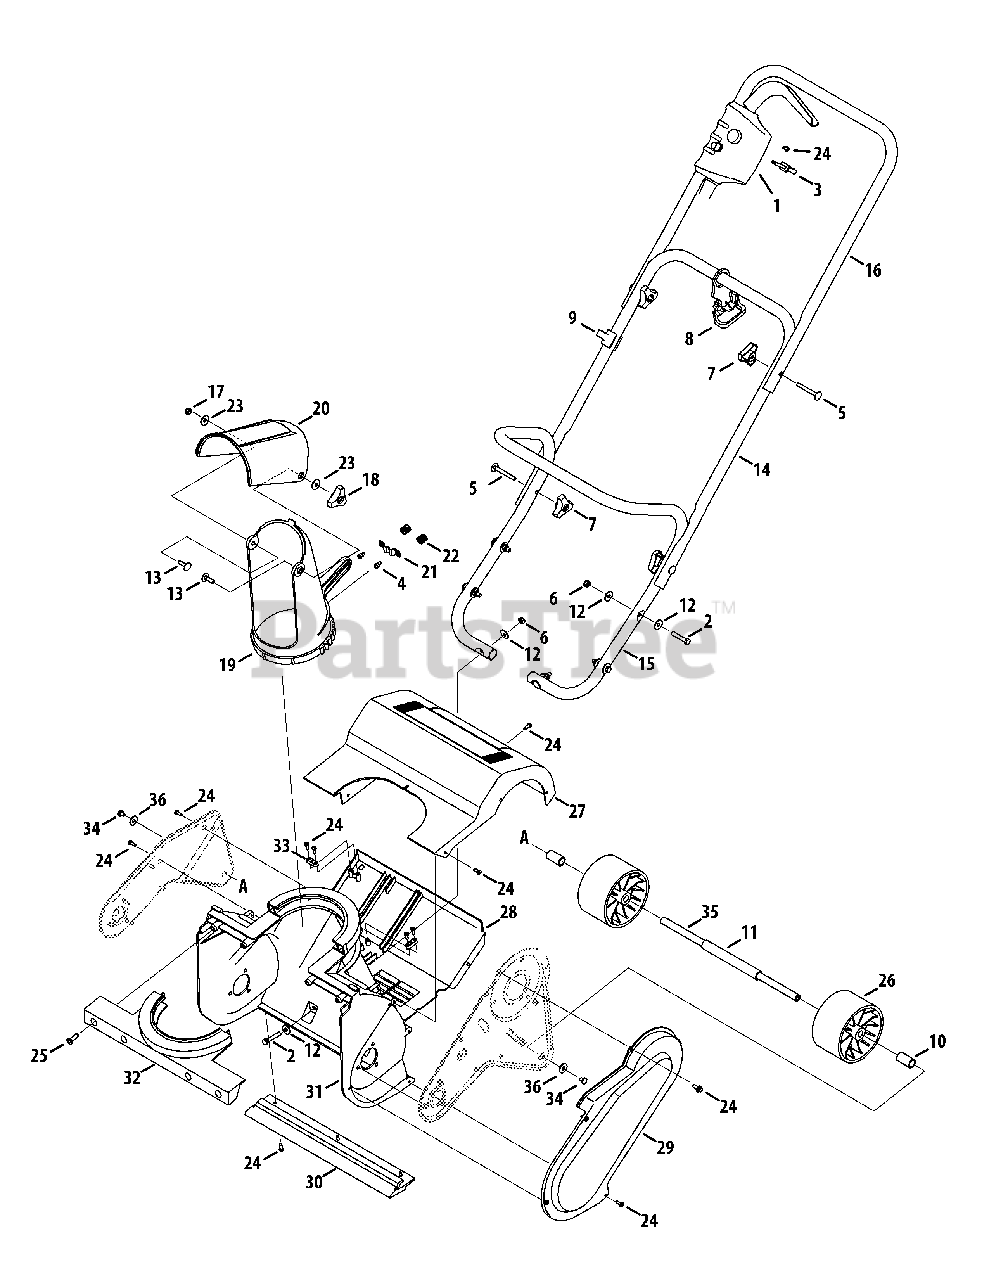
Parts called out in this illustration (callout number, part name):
1	Switch, Assembly
2	Screw, M6-1, 35.00
4	Screw, Shoulder, 6.12 x 4.00
5	Screw, Carriage, M6-1,45, Cl 8.8
6	Nut, Hex Lock, M6-1, Nylon
7	Knob, M6
8	Retainer, Cord
9	Cable, Guide
10	Spacer, 13.0 x 17.0 x 30.0
11	Spacer, 13.0 x 17.0 x 134.0
12	Washer, Flat, 6.4 Id x 18 OD
13	Screw, Carriage, M6-1, 20.00
14	Handle, Mid
15	Handle, Lower, Lift Type
16	Handle, Upper
17	Nut, Hex Lock, M6-1
18	Knob, M6
19	Chute, Lower, Snow
20	Chute, Upper
21	Bracket, Chute, Ratchet
22	Spring, Compression
23	Washer, Bell, .265 x .750 x .062
24	Screw, Tap, M4.2 x 1.4 x 13
25	Screw, Tap, M6.3 x 1.8 x 20
26	Wheel, Roller
27	Cover, Top
28	Cover, Engine, Lower
29	Cover, Belt
30	Blade, Scraper
31	Housing, Auger, Red
31	Housing, Auger, Blk
32	Cover, Front, Red
32	Cover, Front, Blk
33	Bracket, Cord, Holder
34	Screw, Hex Screw, M6 x 8mm
35	Shaft, Roller, Wheel
36	Washer, Flat, 6.4 Id x 18 OD
